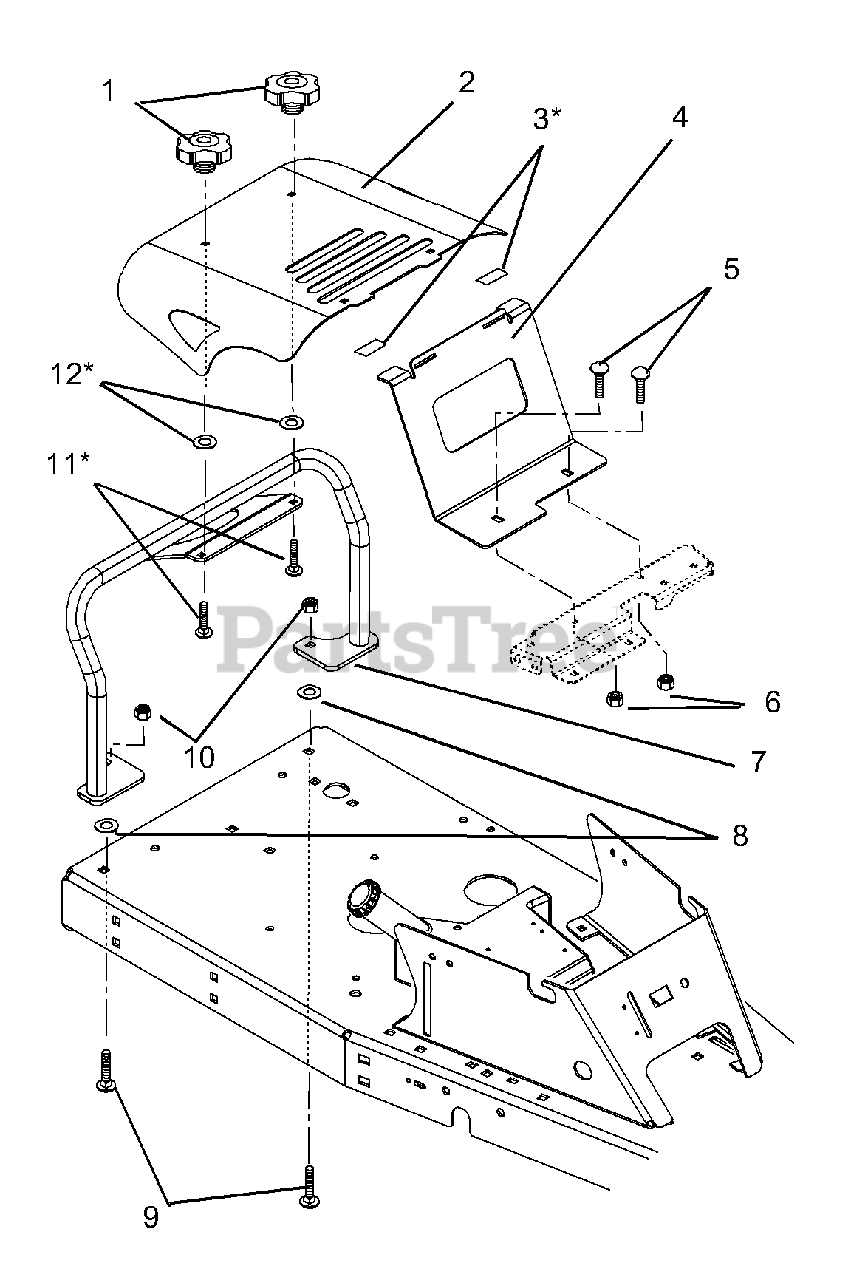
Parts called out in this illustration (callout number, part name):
1	Clamping Knob
2	Engine Hood
3	Foam Tape
4	Hood Support Bracket
5	5/16" x 3/4" Round Head Square Neck Bolt
6	5/16" Flange Nylon Locknut
7	Weldment Tube
8	3/8" Push Nut
9	3/8" x 1" Round Head Square Neck Bolt
10	3/8" Flange Nylon Locknut
11	5/16" x 1" Round Head Short Square Neck Bolt
12	5/16" Push Nut
